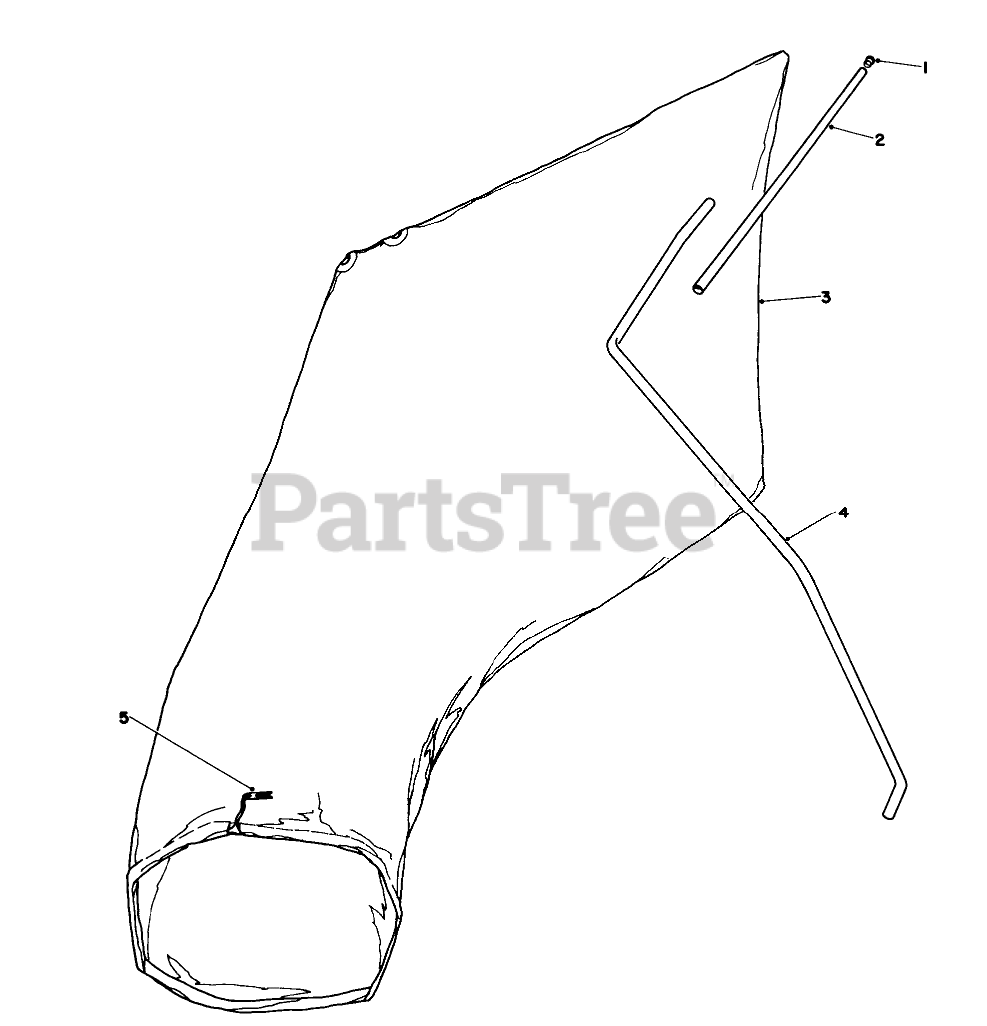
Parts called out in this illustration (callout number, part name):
2	BAG HANGER TUBE
3	Bag (Incl. Ref. #5)
4	HANGER ROD
5	BAG CORD FASTENER
